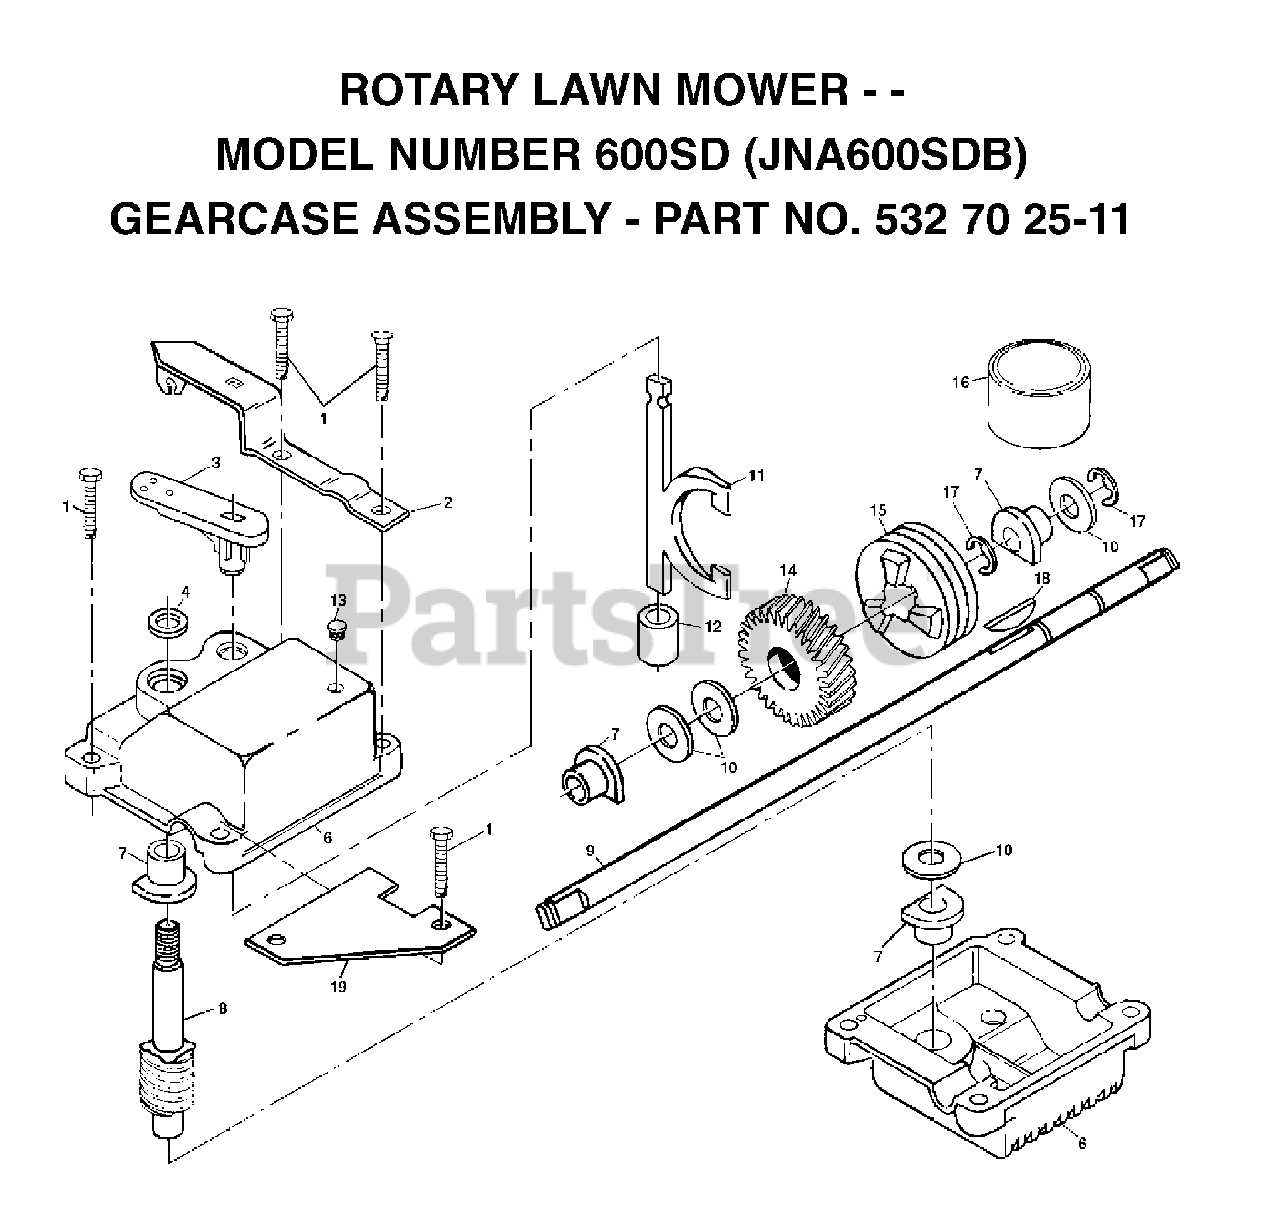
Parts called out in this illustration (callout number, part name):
1	SCREW
2	BRACKET
6	GEAR CASE
8	WORM SHAFT
9	DRIVE SHAFT, 20-5/8"
10	THRUST WASHER
11	YOKE CLUTCH
14	GEAR.HELICAL
15	CLUTCH JAW
16	GREASE
18	HI PRO KEY
19	BRACKET SPRING
